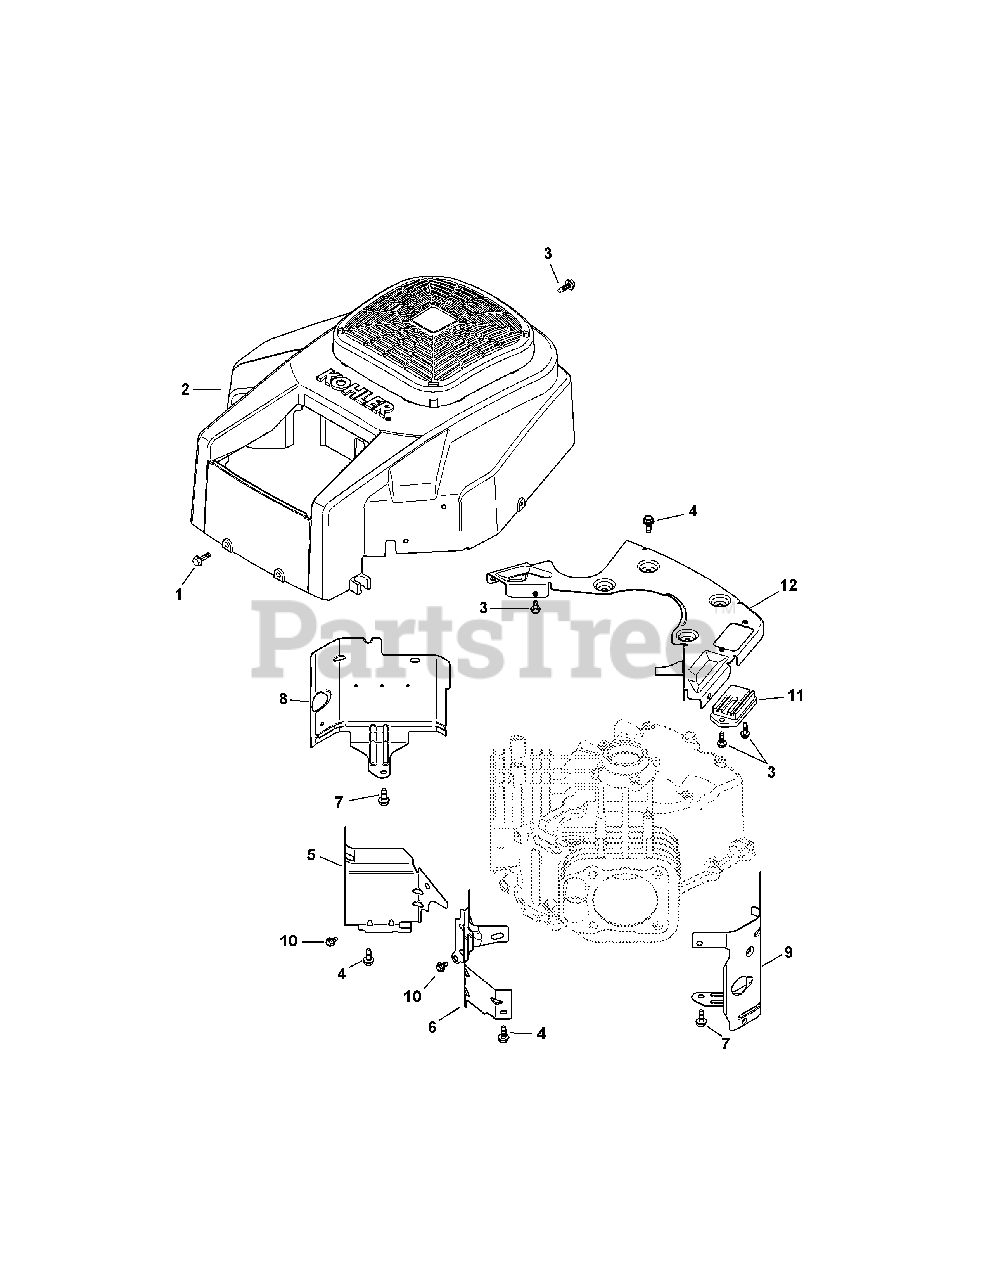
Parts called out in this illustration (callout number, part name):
1	Screw, M6 x 1.7 x 18
2	Blower Housing Kit
3	Flange Screw, M5 x .8 x 16
4	Flange Screw, M6 x 1.0 x 16
5	Valley Baffle, #1 Cylinder
6	Valley Baffle, #2 Cylinder
7	Flange Screw, M6 x 1.0 x 10
8	Cylinder Barrel Baffle, #1 Side
9	Cylinder Barrel Baffle, #2 Side
10	Flange Screw, M5 x .8 x 10
11	Regulator/Rectifier
12	Backing Plate Kit
NS	Fixed Guard Decal
